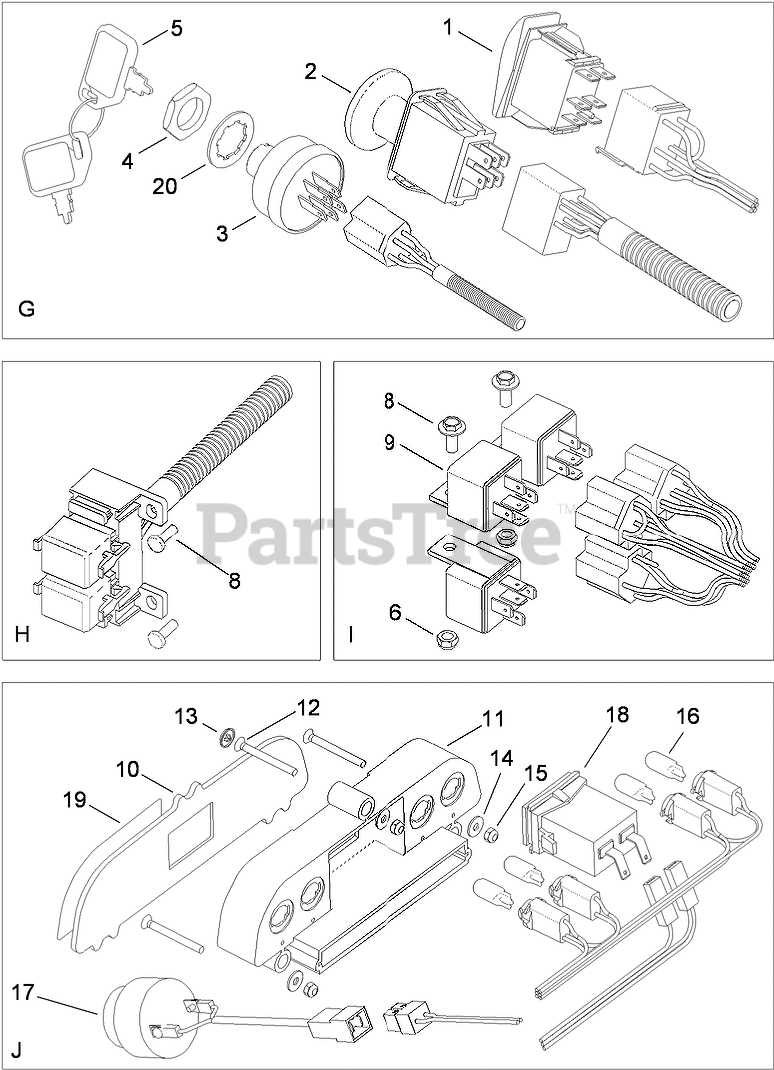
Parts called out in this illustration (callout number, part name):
1	SWITCH-CRUISE
2	SWITCH-PTO
3	SWITCH-IGNITION
4	NUT-HH
5	KEY-IGNITION
6	NUT-LOCK
8	SCREW-HEX
10	LENS-DASH
11	HOUSING-LIGHT, INDICATOR
13	CAP-SCREW
14	WASHER
15	NUT-HEX
17	BUZZER
18	HOURMETER
19	DECAL-DASH
20	WASHER-TOOTH, INTERNAL
